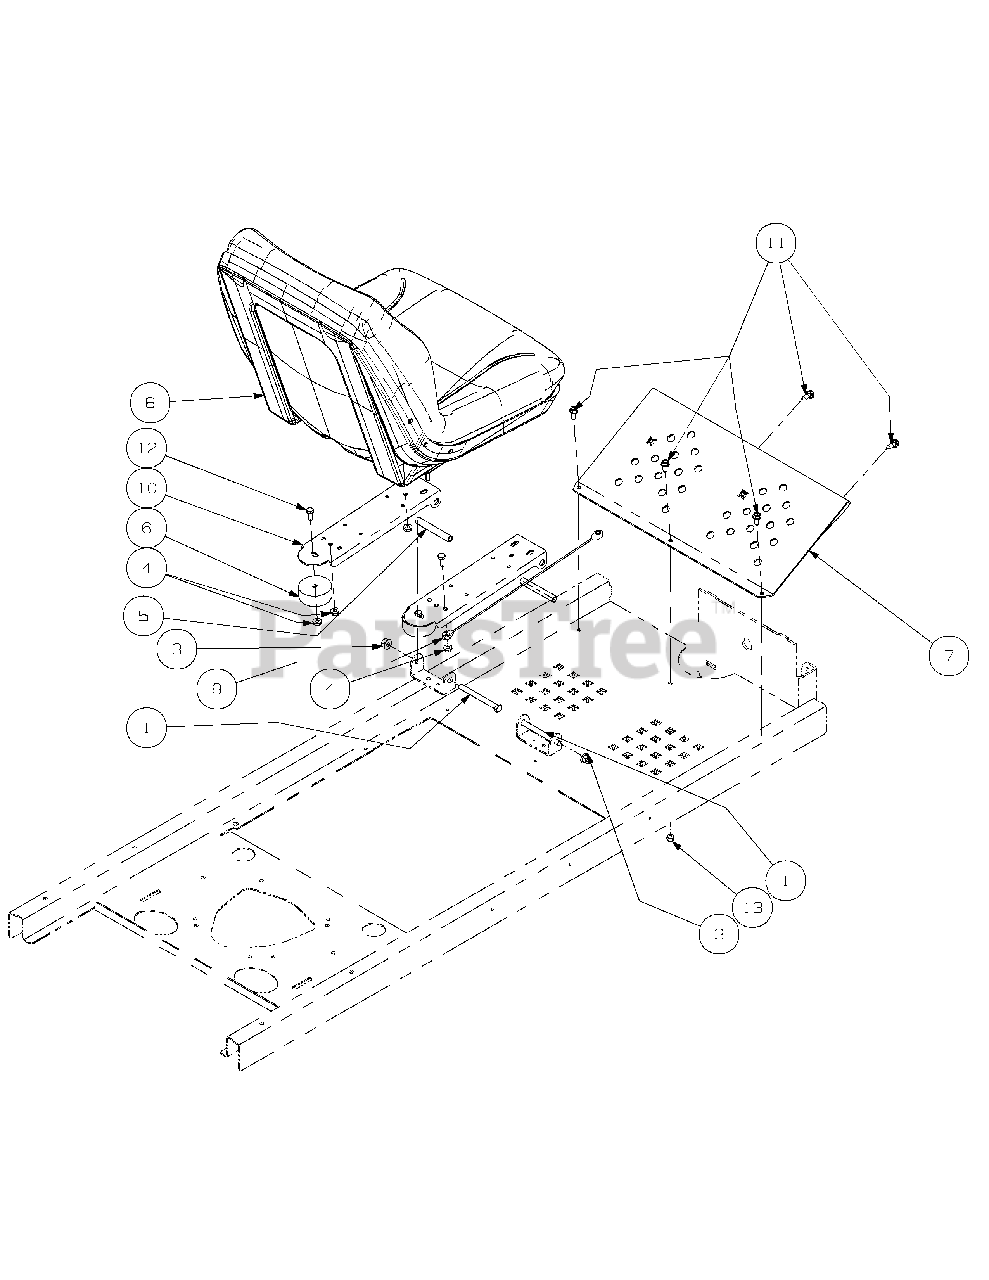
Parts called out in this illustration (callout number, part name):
1	Hex Cap Screw, 3/8-16, 4.00
2	Hex Cap Screw, 5/16-18 x 3/4
3	Flange Lock Hex Nut, 3/8-16
4	Nut, 5/16-18, Hex Flange Lock
5	Spacer, .370 ID x .500 OD x 3.45
6	Bumper, 2.50 OD x 1.13 Long
9	Lift Cable
11	Self Tapping Screw 5/16-18 x .750
12	Hex Cap Screw, 5/16-18 x .75
13	Nylock Nut, 5/16-18
